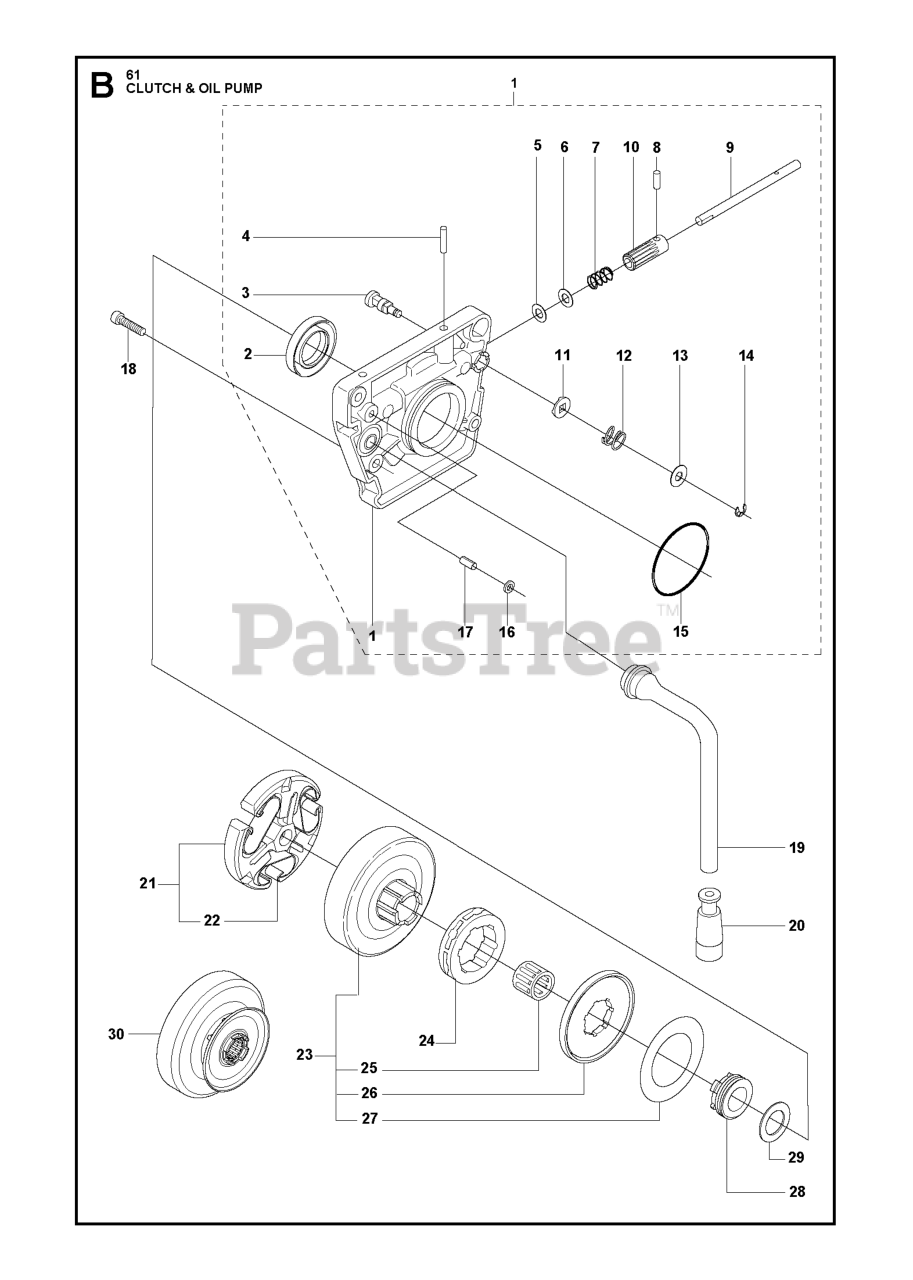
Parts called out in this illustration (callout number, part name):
2	SEALING RING
3	CONTROL SCREW
4	PARALLEL PIN 3X18
5	WASHER 5.1X8.5
6	WASHER 5.1X8.5
10	GEAR WHEEL
14	E-RING 3.2
17	SPRING PIN 3X6
18	SCREW MC6S 4X16
20	OIL SCREEN
23	CLUTCH DRUM
23	CLUTCH DRUM ASSY
24	68210 RIMSPROCKET
24	22273 Sprocket 3/8"x8T
25	SUPPORT BUSHING
26	DUST PROTECTION
28	WORM WHEEL
29	WASHER 13.1X20
30	CLUTCH DRUM ASSY 3/8-7T
